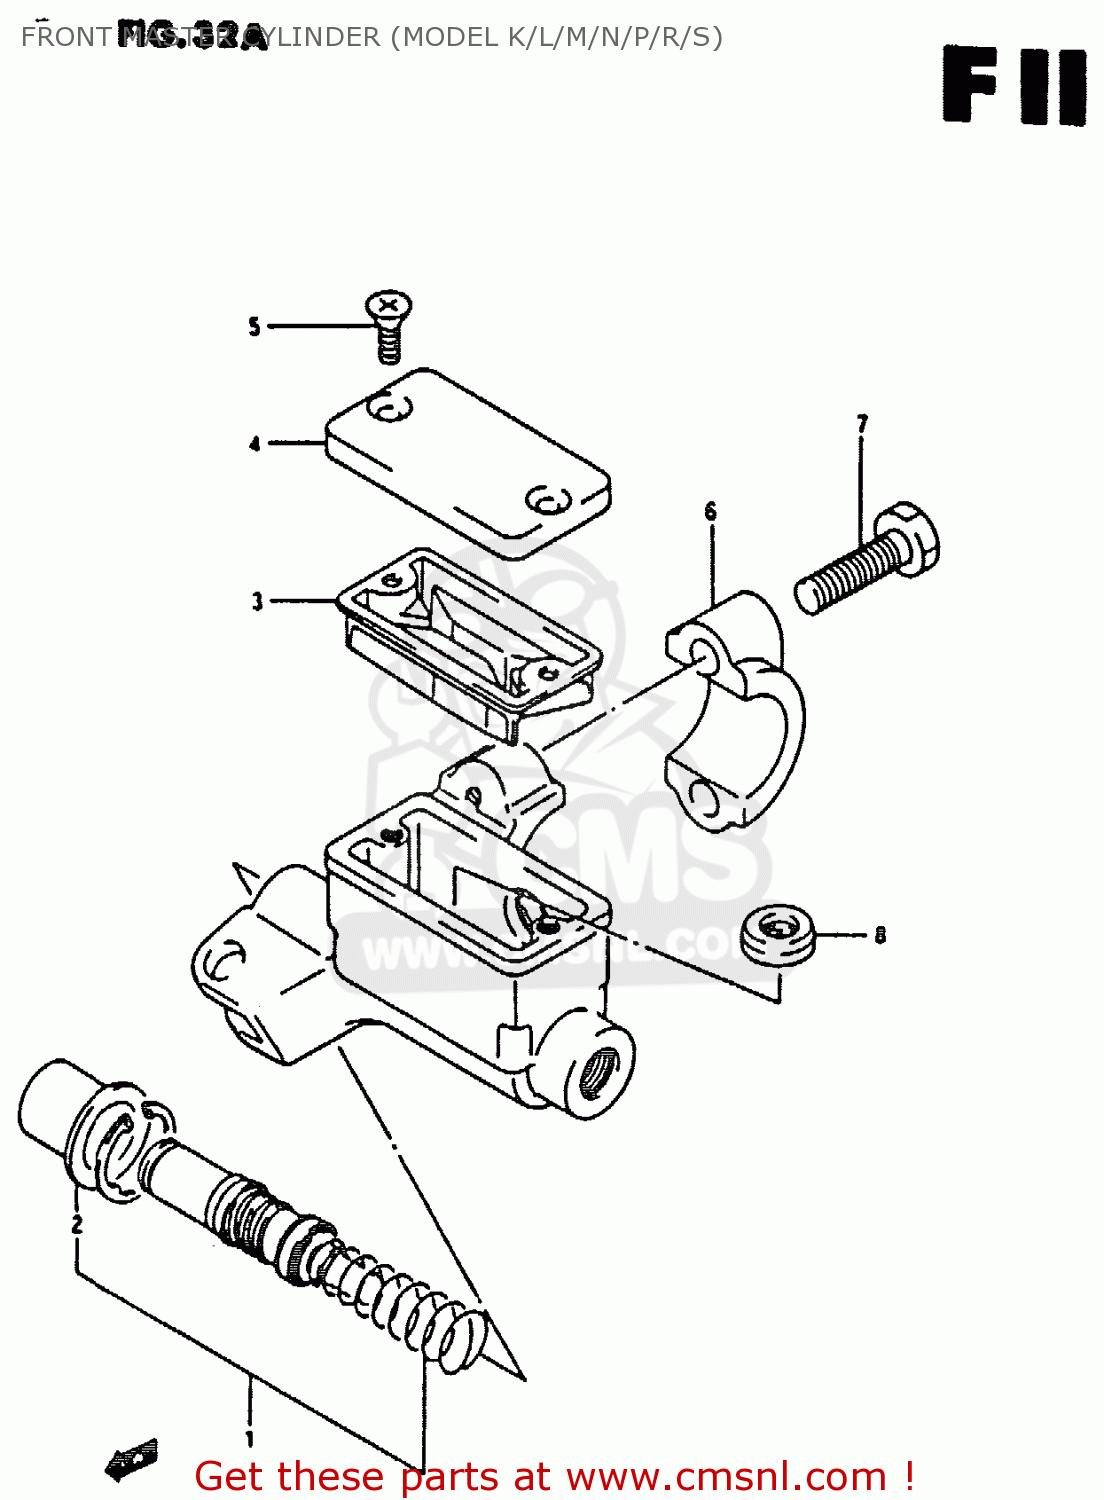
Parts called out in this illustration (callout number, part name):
1	PISTON & CUP SET
2	BOOT
3	DIAPHRAGM
4	CAP
5	SCREW
6	HOLDER
7	BOLT
8	WASHER
9	SEPARATOR
